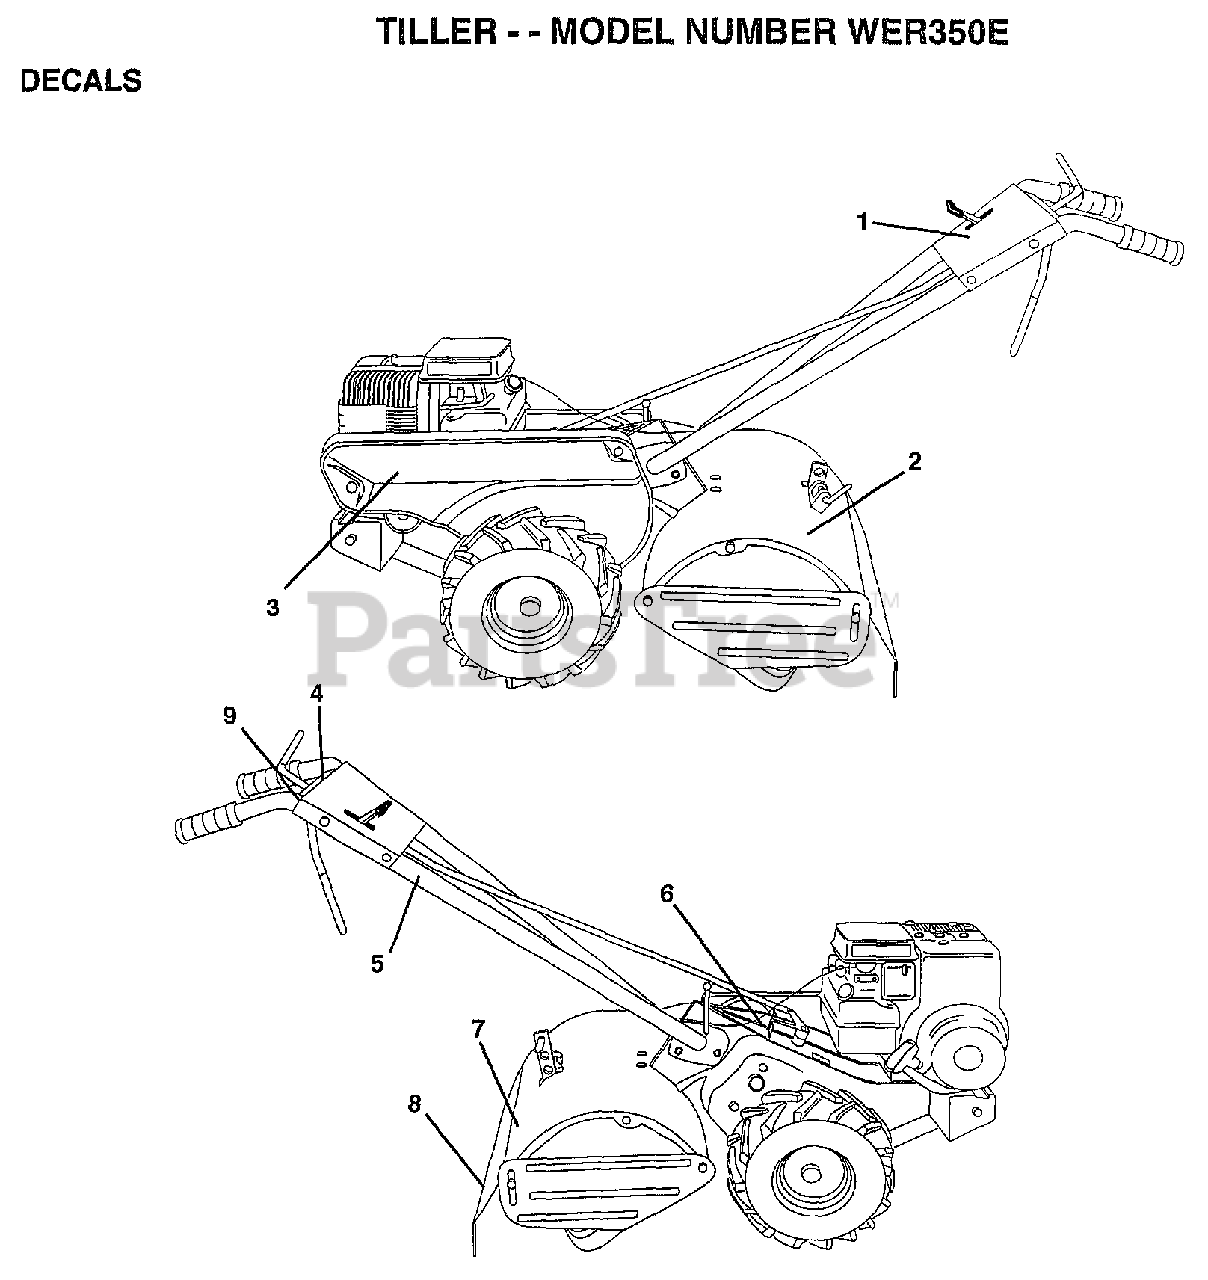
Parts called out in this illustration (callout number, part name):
2	DECAL.DESCRIPTION
5	DECAL TI
6	DECAL CRT
7	DECAL.CAUTION
9	DECAL REVERSE
